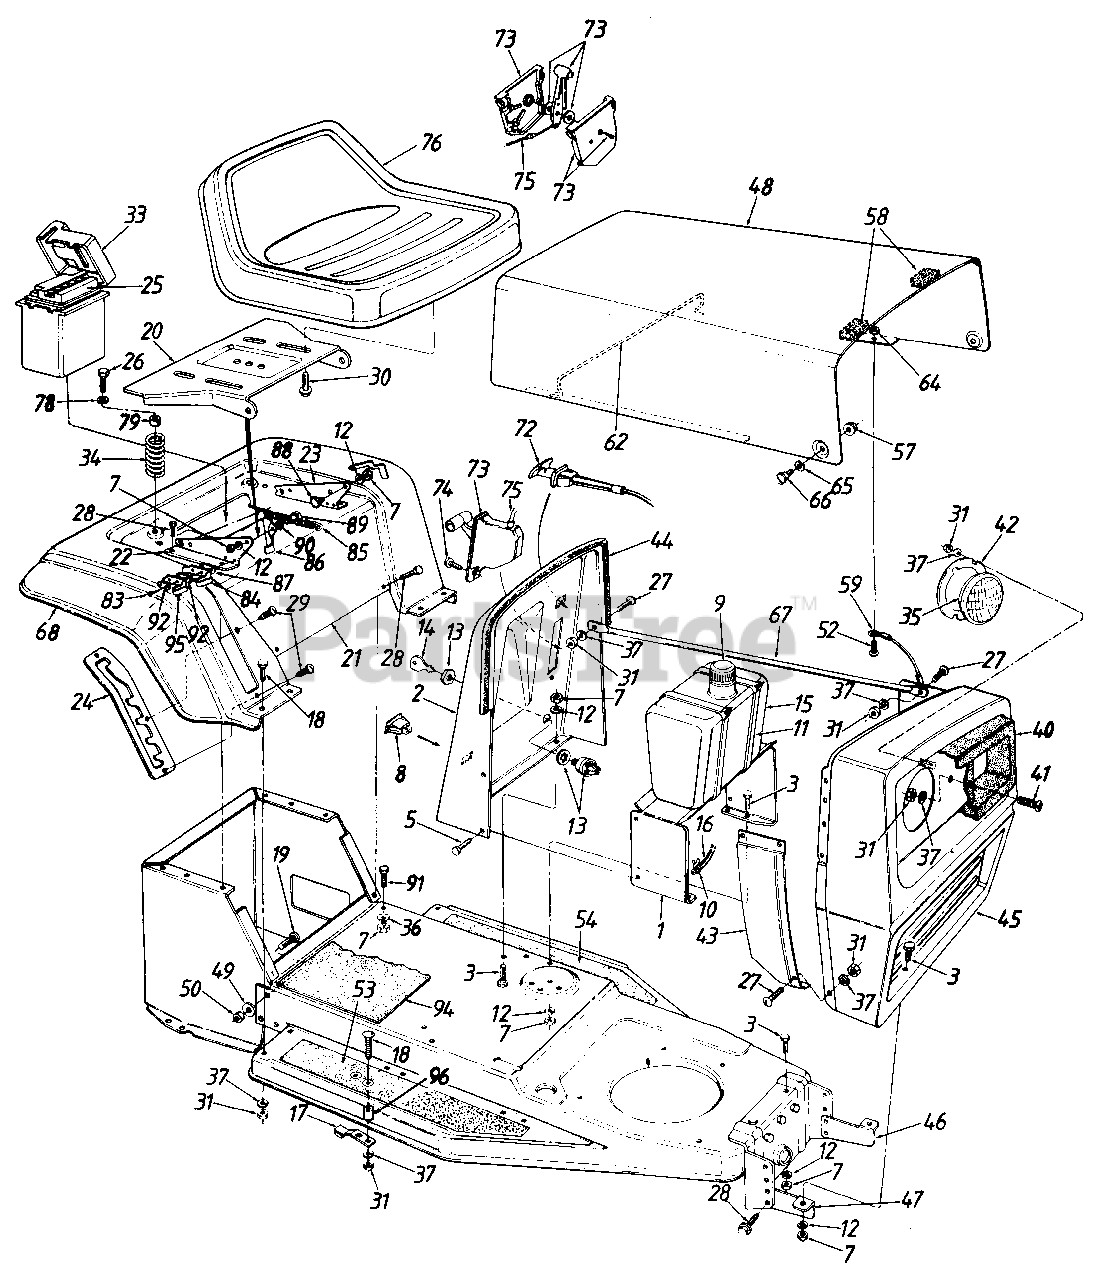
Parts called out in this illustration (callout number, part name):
1	Dash Panel Support Brkt.
5	Hex AB-Tap Scr. 1/4 x .62/
7	Hex Nut 5/16-18 Thd.
8	Light Switch
9	Gas Cap
11	Cable Tie
12	L-Wash. 5/16" I.D.
13	Ignition Switch
14	Ignition Key
15	Fuel Tank
16	Gas Line-15" Lg.
17	Blade Brake Ass'y.
18	Carriage Bolt 1/4-20 x 1.25"
19	Ribbed Neck Bolt 3/8-24 x .8"
20	Seat Pivot Brkt.
25	Battery
26	Hex Self-Tap Screw 5/6-18 x 1 .25 Lg.
27	Truss Mach. Scr. 1/4-20 x .75 Lg.
28	Hex AB-Tap Scr. 5/16 x .75 Lg.
29	Torx Mach. AB-Tap Scr. 1/4 x .62" Lg.
30	Hex Self-Tap Scr. 3/8-16 x .75" Lg.
31	Hex Nut 1/4-20 Thd.
33	Battery Box w/Cover
34	Compression Spring
35	Headlight
36	Bell-Wash. 5/16" I.D.
37	L-Wash. 1/4" l.D.
41	C-Sunk Mach. Scr. 1/4-20 x 1.5"
42	Headlight Retainer
43	Side Panel-R.H.
44	Trim Strip 31" Lg.
47	Grille Mtg. Brkt.-R.H.
50	Hex L-Nut 3/8-24 Thd.
52	Truss Mach. Scr. #10-24 x .5" Lg.
53	Foot Pad-R.H.
54	Foot Pad-L.H.
57	Lock Nut 1/4-28 Thd.
64	Hex Sems Nut #10-24 Thd.
65	Spr. Wash. 39" l.D. x .62" O.D.
66	Shld. Bolt
67	Grille Support
68	Trim Strip 81" Lg.
72	Choke Control
73	Throttle Control Box
74	Truss AB-Tap Scr. #10 x .5"
75	Throttle Wire
76	Seat Assembly
78	Flat Wash. .344" I.D. x .88n
83	Hex Tap Scr. #8 x .5" Lg.
84	Safety Switch
85	Ext. Spring 5.31" Lg.
86	Seat Lift Brkt.
87	Insulator Boss Plate
88	Shld. Bolt .437" Dia. x .162" Lg.
89	Shld. Bolt .437" Dia. x .268" Lg.
90	Spr. Wash. .445" I.D. x .75" O.D.
91	Hex Wash. Hd. Scr. 5/16-18 x 52" Lg.
92	Insulator Plate
94	Foot Pad-Center
95	Safety Switch
96	Spacer .315" I.D. x .52"
